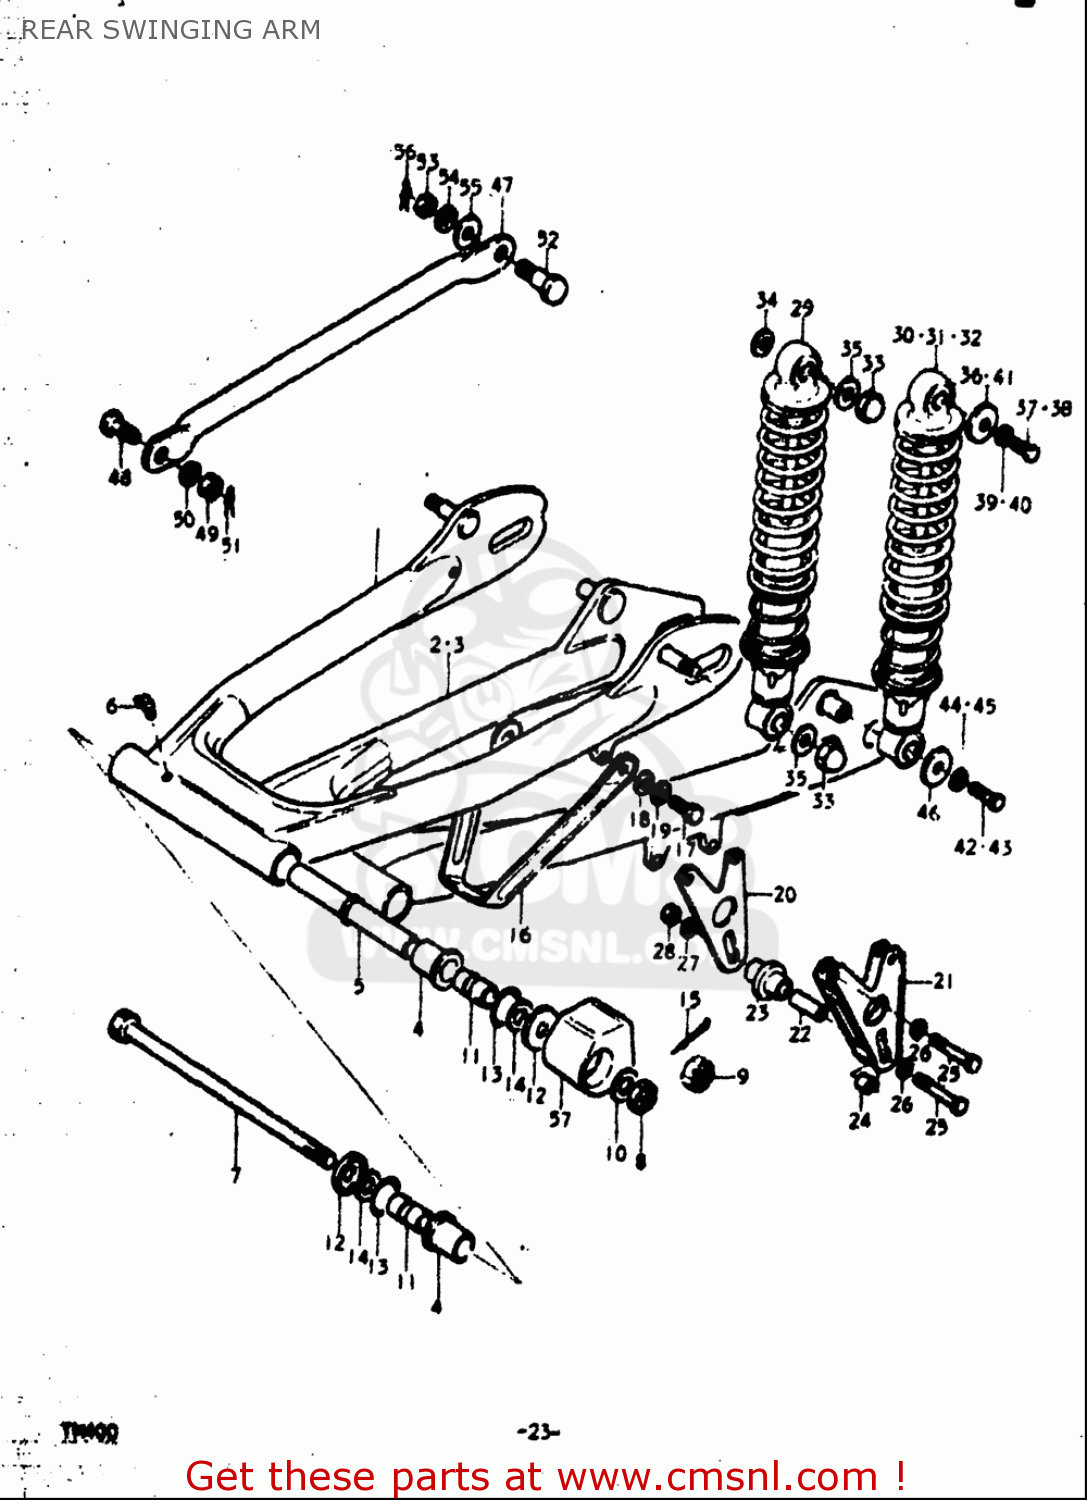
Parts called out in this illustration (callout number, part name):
4	BUSH
5	SPACER,SWING ARM,CENTER
6	NIPPLE,GREASE
8	NUT
9	NUT
10	WASHER
11	SPACER
12	COVER
13	O RING(D:2,ID:24.5)
14	WASHER(12.5X24X2.3)
15	COTTER PIN
17	BOLT
18	WASHER
19	WASHER,LOCK
22	SPACER
24	SPACER(6.5X12X6.9)
25	BOLT
26	WASHER,LOCK
27	WASHER
28	NUT (6MM)
33	NUT
34	WASHER
35	WASHER (10.5X24X2.3)
37	BOLT
38	BOLT 12X50
39	WASHER,LOCK
40	WASHER
41	WASHER(6.5X28X1.6)
42	BOLT
43	BOLT(12X33)
44	WASHER,LOCK
45	WASHER
46	WASHER(6.5X28X1.6)
48	BOLT(8X22.5)
49	NUT
50	WASHER,LOCK
51	CLIP
52	BOLT(10X32.5)
53	NUT
54	WASHER,LOCK
55	WASHER(12.5X24X1.6)
56	CLIP
57	BUFFER,CHAIN TOUCH DEFLECTOR
